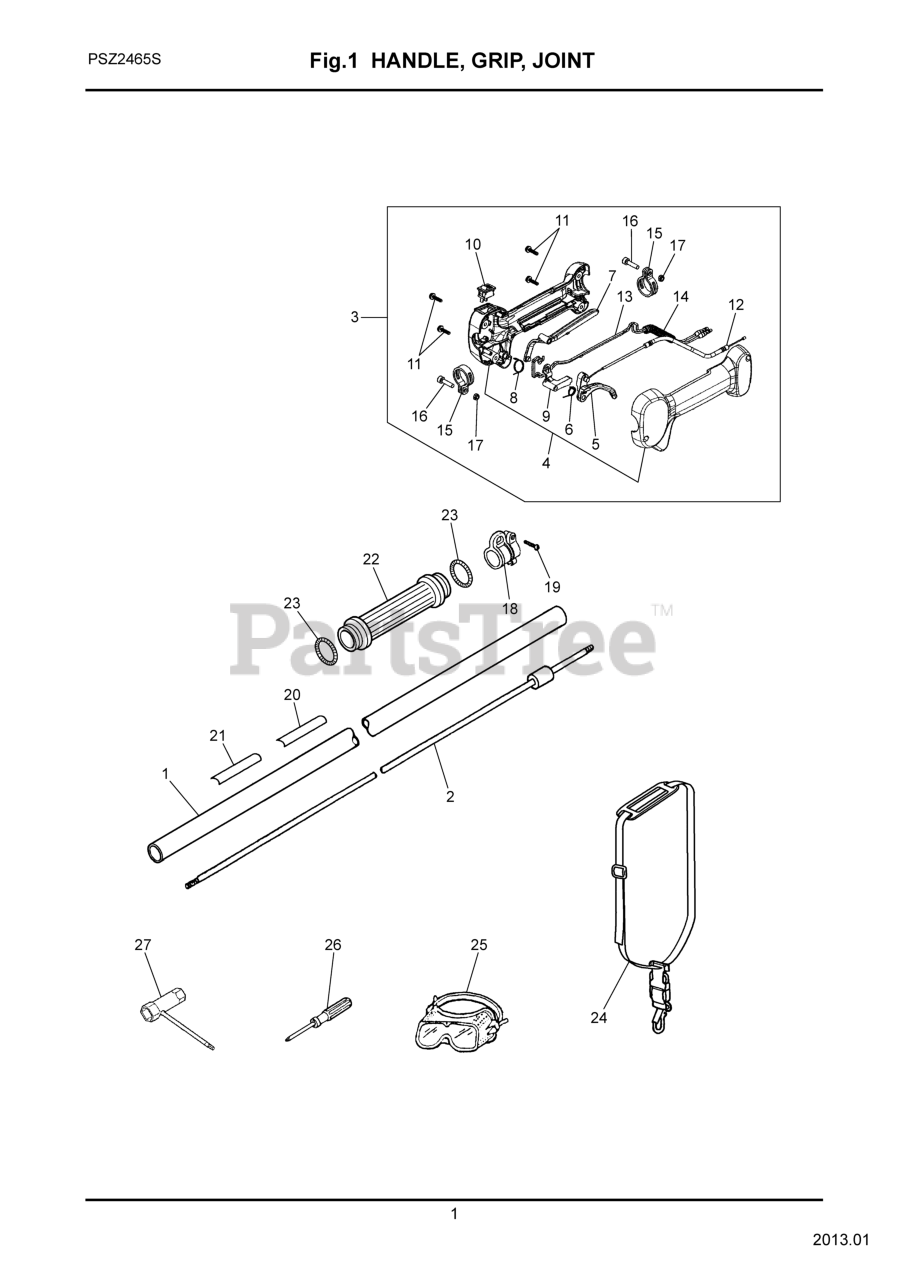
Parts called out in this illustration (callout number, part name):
1	PIPE COMP
2	SHAFT
3	GRIP ASSY
4	GRIP HALF SET
5	LEVER, THROTTLE
6	SPRING, THROTTLE
7	LEVER, SAFETY
9	LEVER JOINT
13	CORD - C
17	NUT
18	HANGER COMP.
20	DECAL NAME
21	LABEL CAUTON FOR BC
24	STRAP ASSY
25	GOGGLExxx (RPLS
27	WRENCH COMBO
